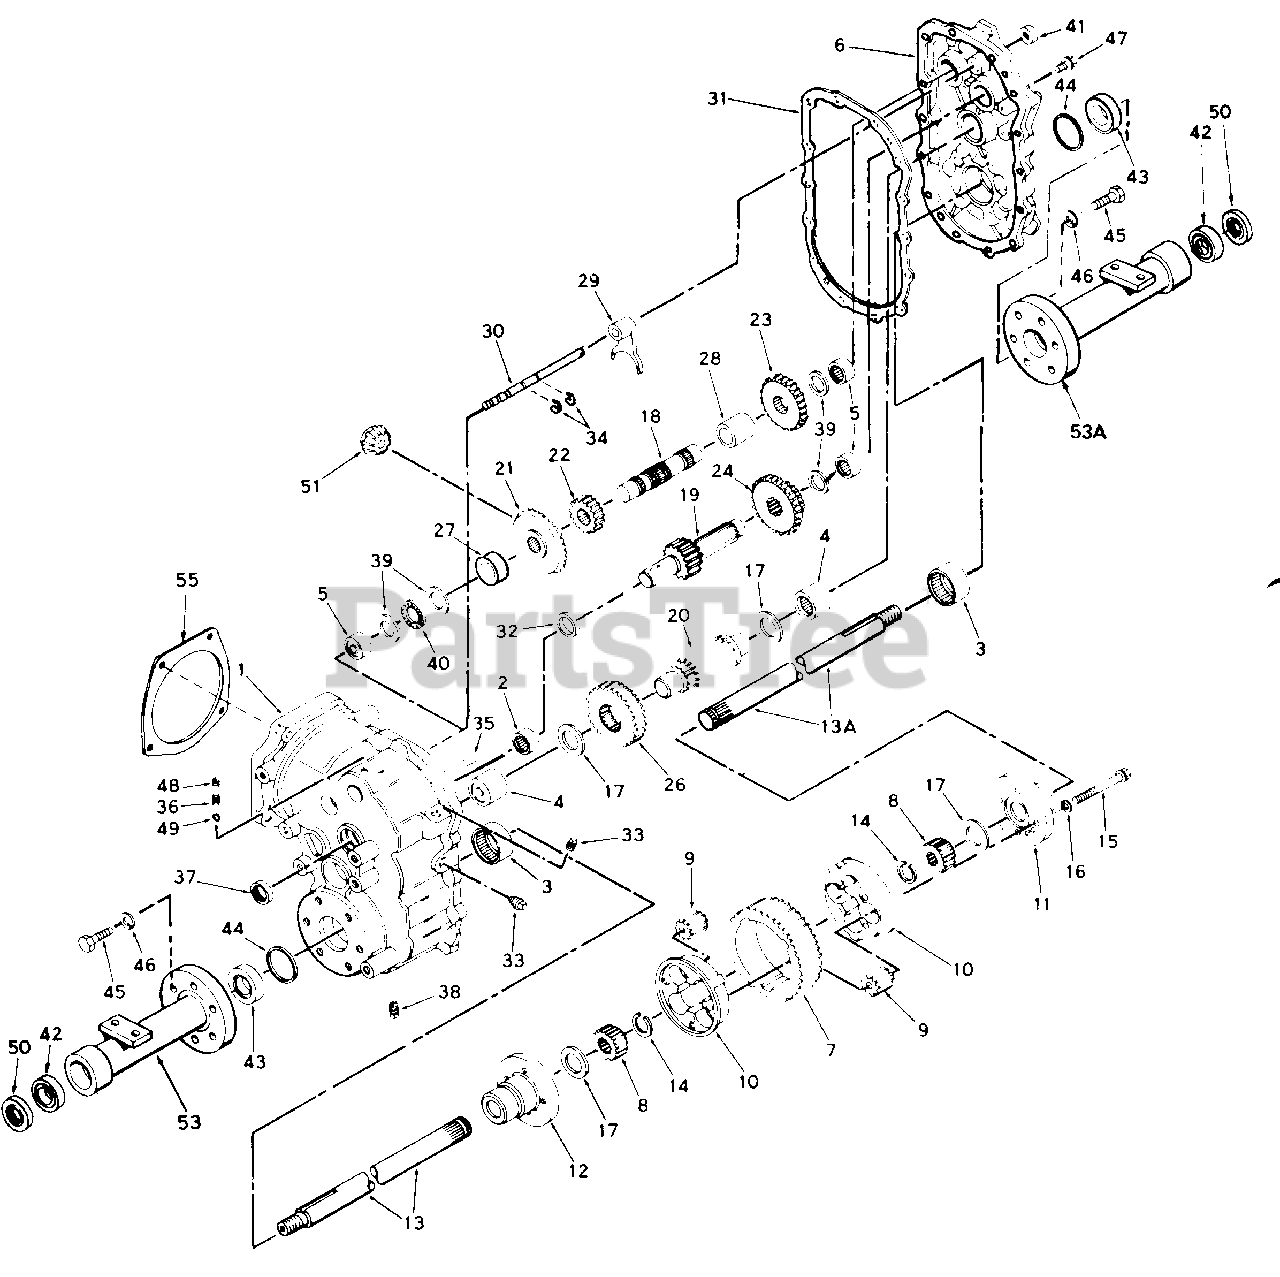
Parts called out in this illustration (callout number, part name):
1	Case Ass'y., Transaxle
2	Bearing, Needle
3	Bearing, Needle
4	Bearing, Needle
5	Bearing, Needle
6	Cover Ass'y., Transaxle
7	Gear, Ring
8	Gear, Side
9	Gear, Pinion
10	Core, Body
11	Carrier Differential
12	Carrier, Differential
13	Axle, (18 17/64" Long)
13A	Axle, (15 29/64" Long)
14	Ring, Snap
15	Screw, Hex Hd. Mach., 3/8-16 x 3-3/8
16	Lock Washer, 3/8"
17	Washer, Thrust
18	Shaft, Counter
19	Shaft, Brake
20	Pinion, Output
21	Gear, Bevel (30 Teeth)
22	Gear, Spur (16 Teeth)
23	Gear, Spur (23 Teeth)
24	Gear, Cluster (20 and 27 Teeth)
26	Gear, Output (37 Teeth)
27	Spacer (55/64" Long)
28	Spacer (1 19/32" Long)
29	Fork, Shift
30	Rod, Shift
31	Gasket, Case and Cover
32	Spacer
33	Plug, Pipe
34	Ring, Snap
35	Pin, Dowel
36	Spring
37	Seal, Oil
38	Plug, Magnetic Drain
39	Washer, Thrust
40	Bearing, Thrust
41	Seal, Oil
42	Bearing, Ball
43	Bearing, Thrust
44	Seal, Square Cut
45	Screw, Hex Hd. Mach., 1/2-13 x 11/2
46	Lock Washer, 1/2"
47	Screw, Hex Hd. Thd. [Forming, 5/16-18 x 1
48	Screw, Set 1/4-20 x 1/2
49	Ball, Steel
50	Seal, Oil
51	Pinion, Bevel
53	Housing, Axle (9 1/4" Long)
53A	Housing, Axle (7 5/16" Long)
55	Gasket
